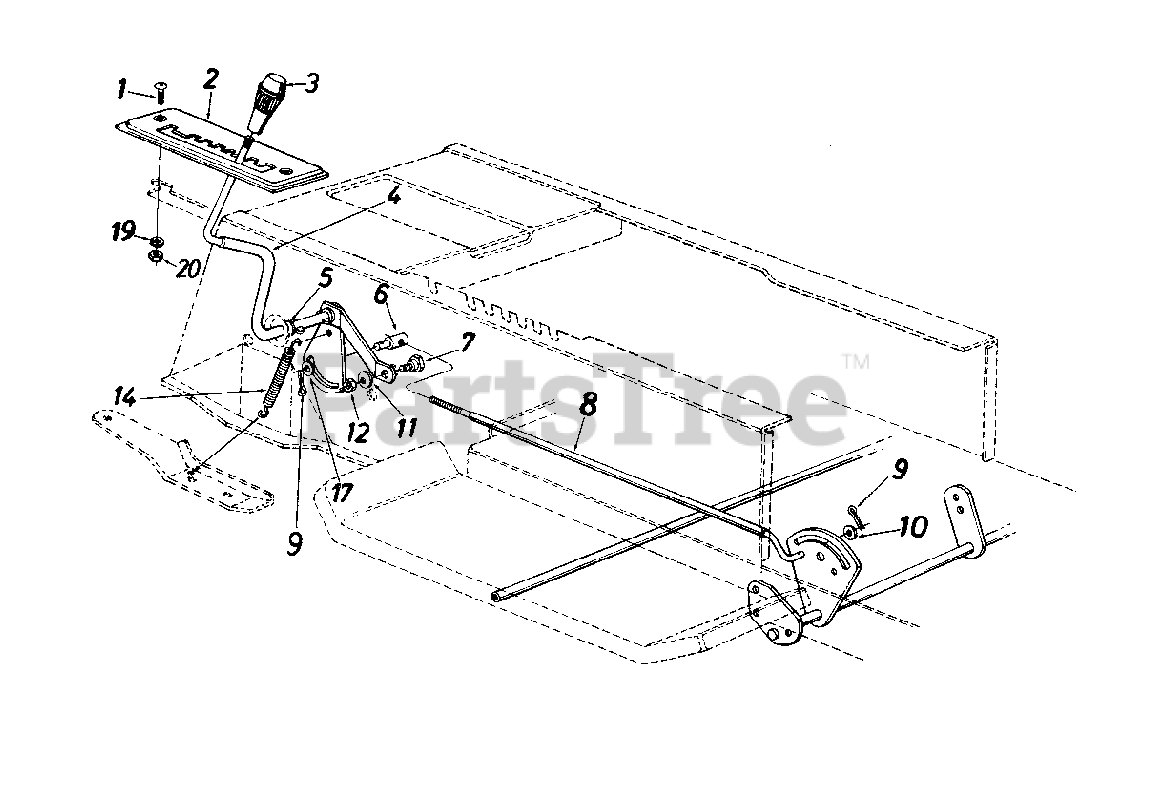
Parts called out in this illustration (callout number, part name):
1	Compression Spring
2	Hex Nut 5/16-18 Thd.
3	L-Wash. 5/16" I.D.
4	Shift Lever Support
5	Ferrule 3/8-24 Thd.
6	Speed Control Rod
7	Spacer 1.56" Lg.
8	Bell-Wash. .505" I.D. x 1"
9	Fl-Wash. .385" I.D. x .87"
10	Speed Selector Lever
11	Shift Knob
12	Spacer 1.46" Lg.
14	Hex Bolt 5/16-18 x 3.25" Lg.
17	Fl-Wash. .34" I.D. x 2.25"
